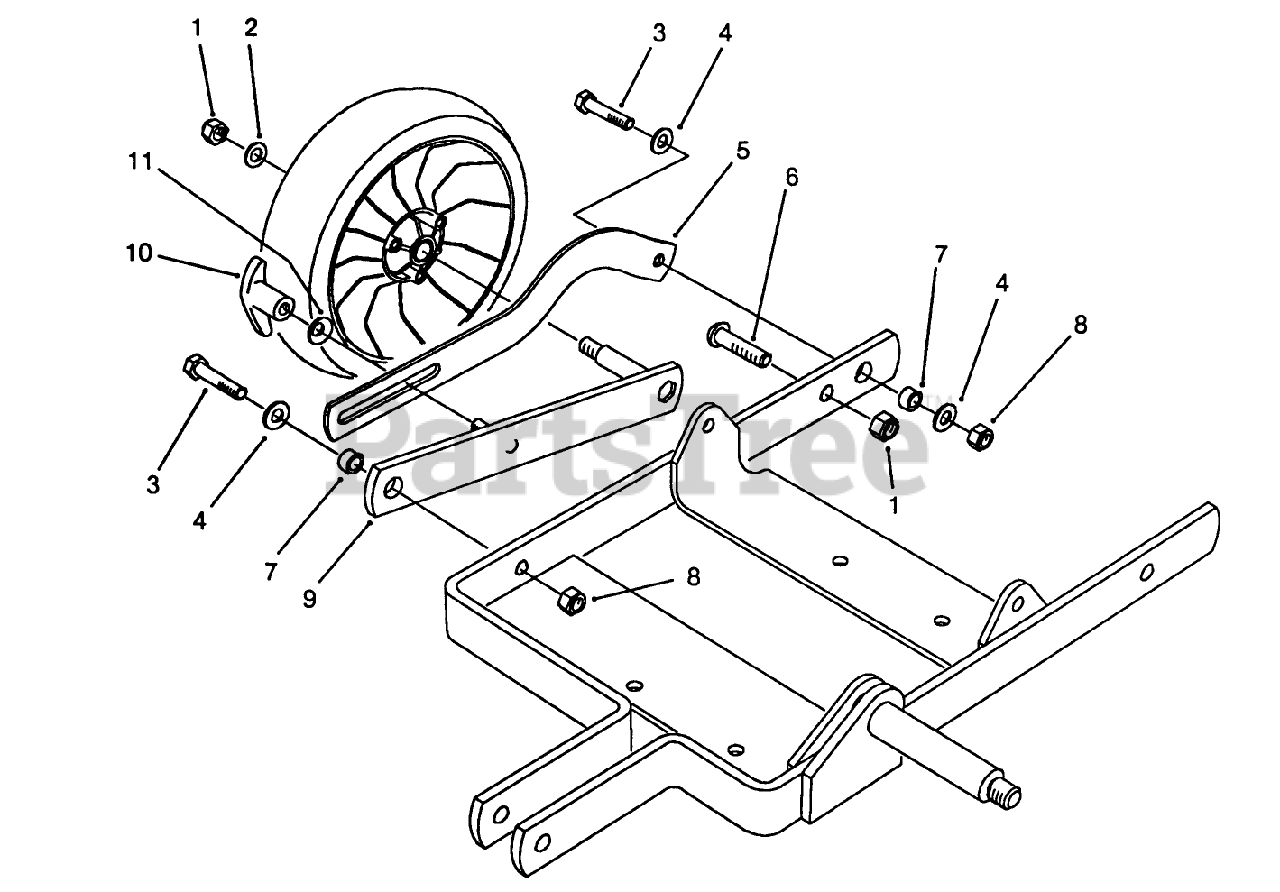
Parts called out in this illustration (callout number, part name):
1	NUT-LOCK
2	WASHER
3	SCREW-HH
4	WASHER-FLAT
5	AXLE LINK
6	3/8-24 X 1.00HEX BU. HD
7	WHEEL MT BUSHING
8	NUT-LOCK, NI
9	WHEEL MOUNT WA
11	BELLEVILLE SPRING WASHE
